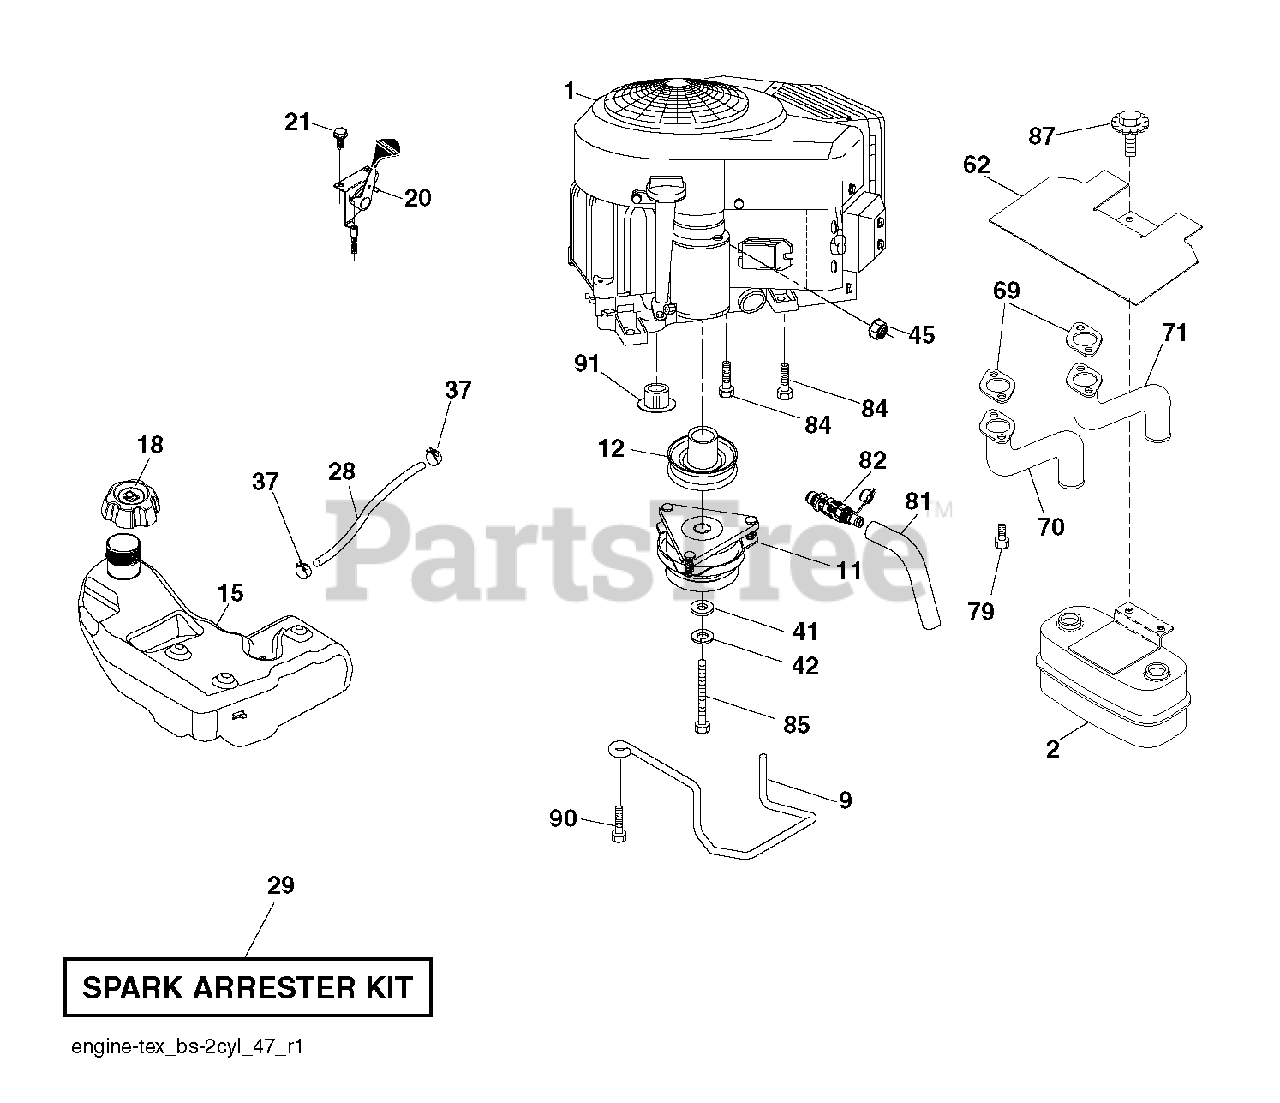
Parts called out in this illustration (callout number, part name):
1	Husqvarna TBD
2	MUFFLER.TWIN.CYL.LOW.TONE
9	KEEPER.BELT.ENGINE.4.2
11	CLUTCH.ELECTRIC.LT.48"*
12	PULLEY.ENGINE.TUFFTORQ
15	TANK.ASSY.3.GAL.EPA
18	CAP.ASM.FL.RITCH.3"E10.SYM.498
20	CONTROL.TH/CK.COBRA.B&S.TWN.
21	SCREW.#10 X 0.750.BOS
28	LINE.FUEL.64"REAR.EMIS
29	KIT.SPARK ARRESTOR 794945 B&S
37	HOSE CLAMP
42	LOCKWASHER
45	NUT
62	SHIELD.HEAT.MUFFLER
69	GASKET.MUFFLER
70	RP.EXHAUST.TUBE.LH.BS/TWIN
71	EXHAUST.TUBE.RH.BS/TWIN
79	SCREW.SOCKET.HEAD.5/16-18
81	TUBE, DRAIN OIL ASM.
82	VALUE.OIL.DRAIN
84	SCREW.3/8-16
85	BOLT HEX 7/16-20X4-1/4"
87	Bolt, 5/16-18 X 1-3/4
90	SCREW 3/8-16X1
91	BUSHING.1.375OD
